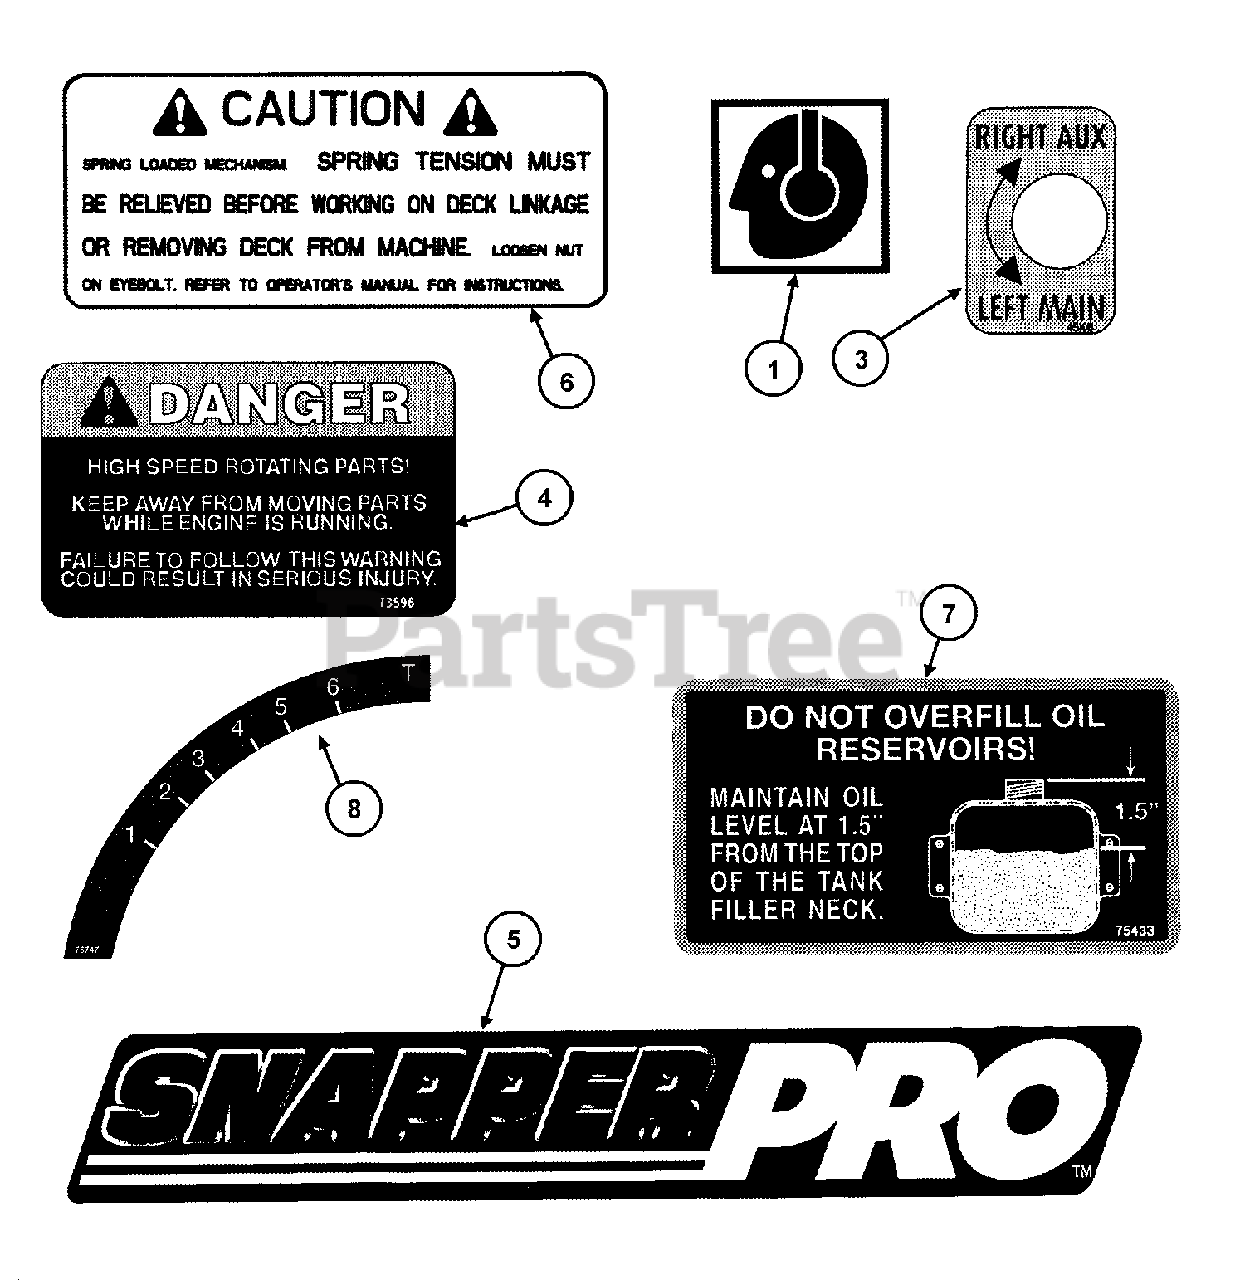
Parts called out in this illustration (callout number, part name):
1	DECAL, Ear Protection
3	DECAL, Tank Selector, MMZ
4	DECAL, Danger- High Speed Rotating Parts
5	DECAL, SNAPPER PRO
6	DECAL, Caution (Spring Mechanism)
7	DECAL, Reservoir Oil Level
8	DECAL, Detent
